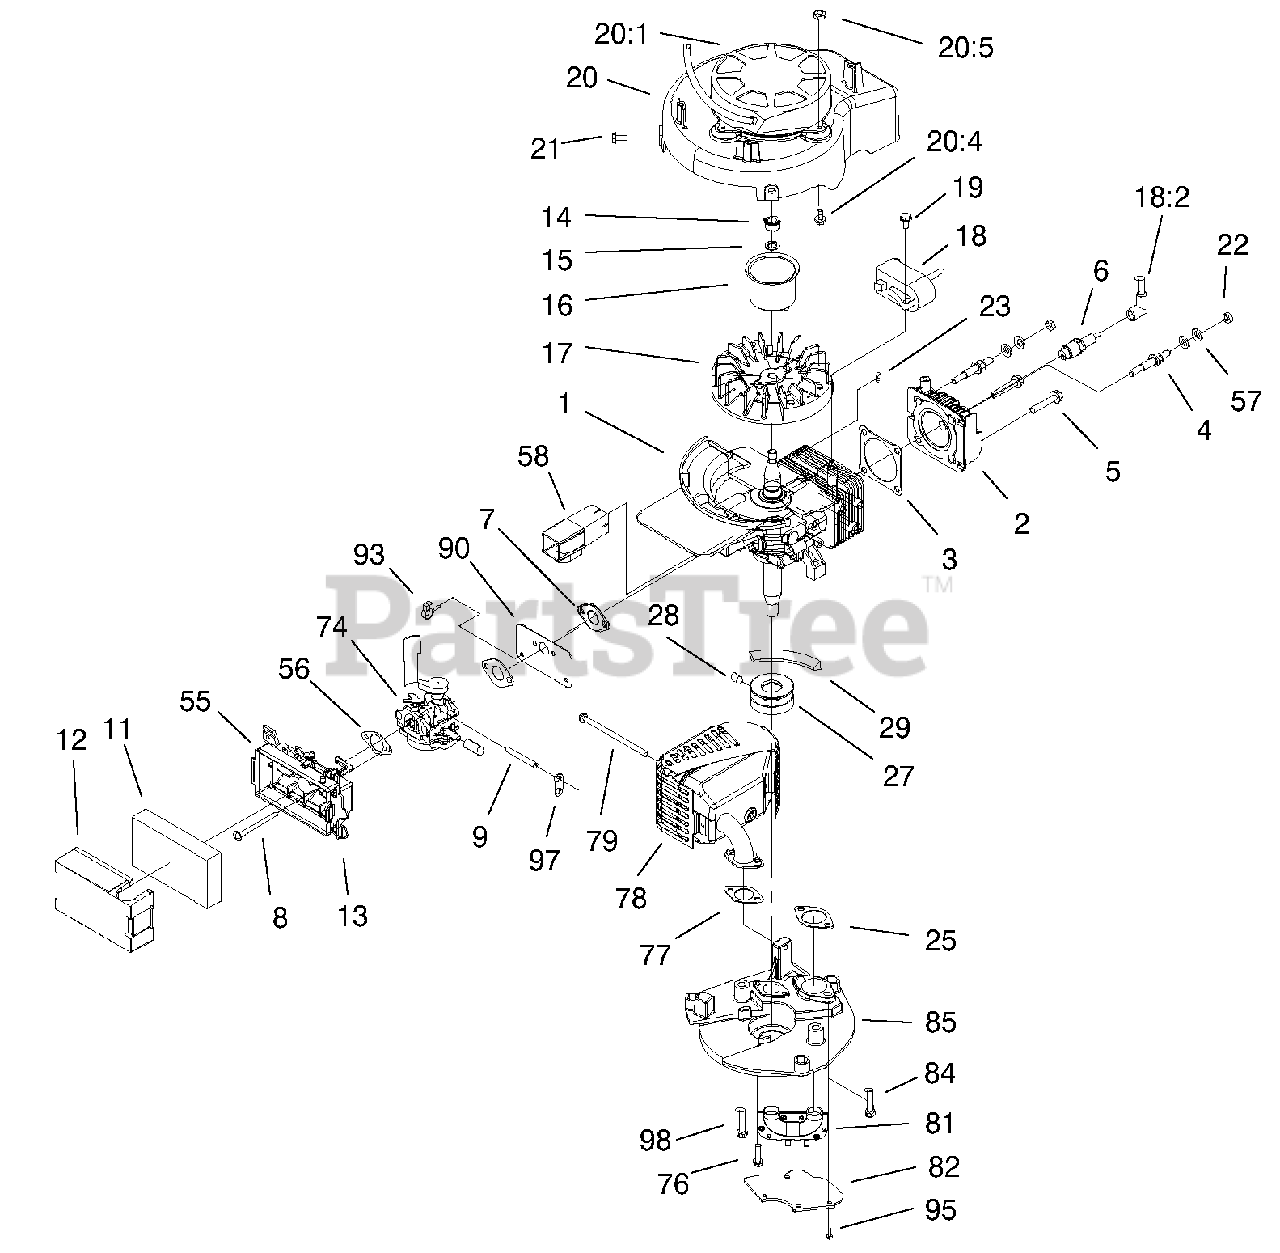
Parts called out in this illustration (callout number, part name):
1	SHORT BLOCK ASM
2	HEAD-CYLINDER
3	GASKET-HEAD
5	BOLT-HEAD
6	SPARK PLUG
7	GASKET-INTAKE
9	HOSE-PRIMER
11	FILTER-AIR
12	COVER-FILTER, AIR
13	RETAINER-COVER, FILTER
15	WASHER-LOCK
16	CUP-STARTER
17	FLYWHEEL (MACH) ELE E
18	MODULE-IGNITION CD
18:2	LEAD-TENSION, HIGH
20	SHROUD-RECOIL
20:1	RECOIL ASM
20:4	SCREW-HWH
20:5	NUT-LOCK
21	SCREW-HH
25	GASKET-EXHAUST
28	SCREW-SET
29	V-BELT E
55	AIR BASE ASM
56	GASKET-FILTER
57	WASHER-BELLEVILLE
58	TUNNEL-INLET
74	CARBURETOR ASM
78	MUFFLER & GUARD AY E
79	BOLT-CONSOLE
81	PIPE-TRANSFER
82	COVER-MUFFLER E
84	SCREW-HH
85	PLATE-MUFFLER
90	SHIELD-CARB E
93	RETAINER-WIRE
95	SCREW-HH
97	HOSE-RETAINER
